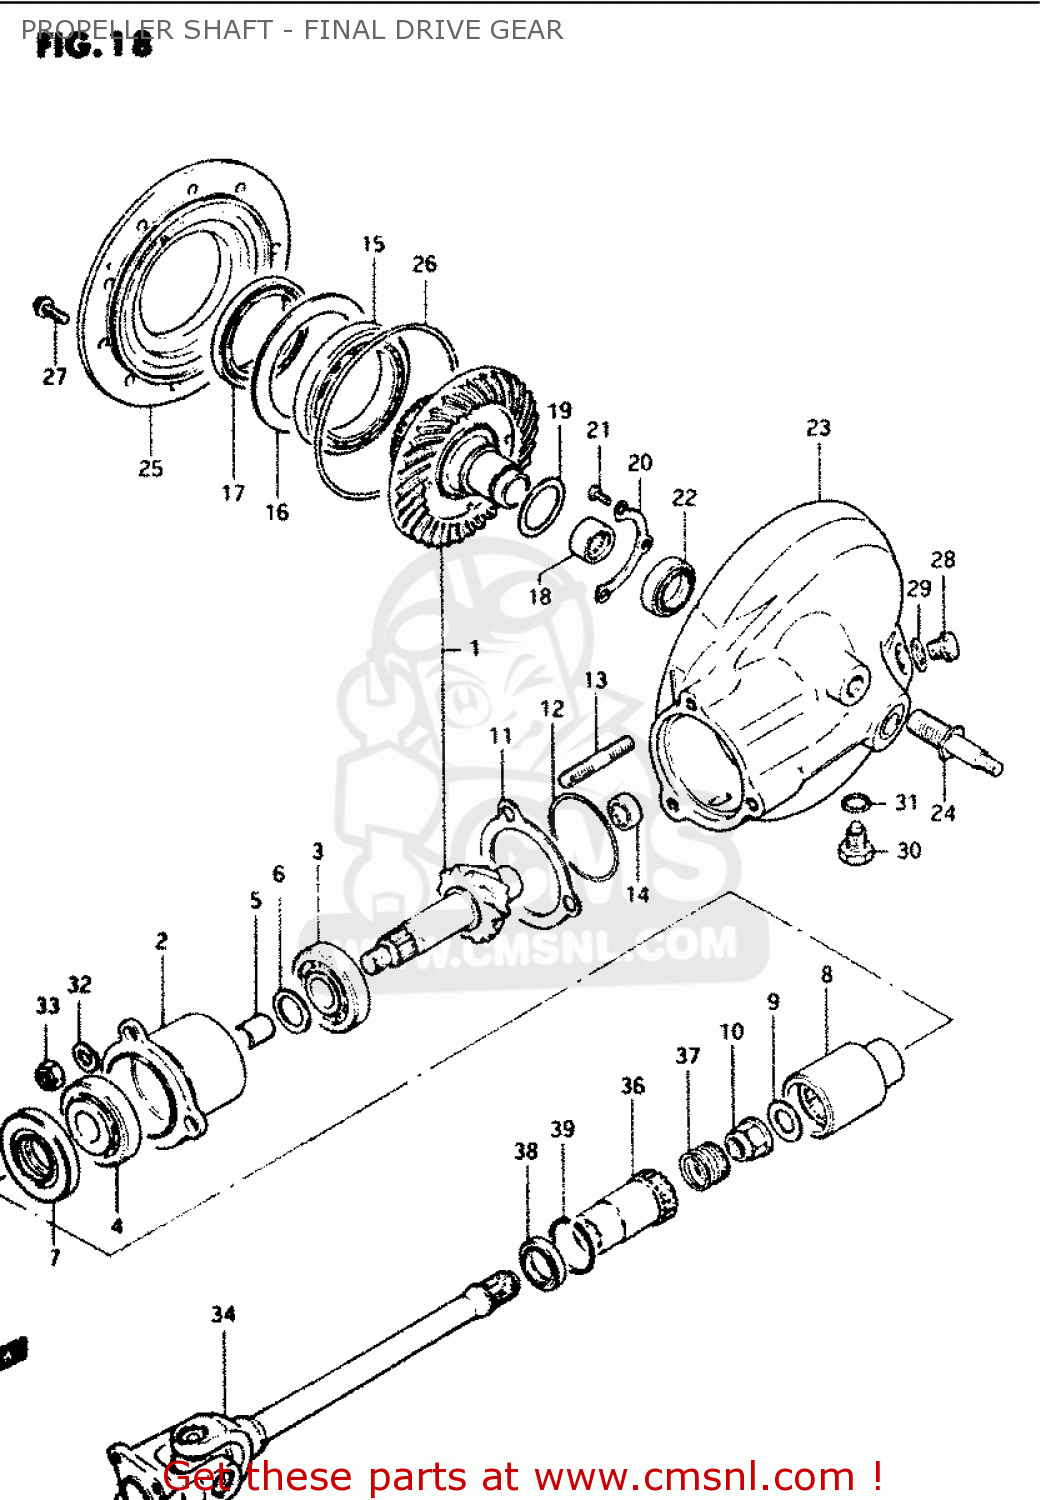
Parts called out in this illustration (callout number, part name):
1	GEAR SET,FINAL BEVEL
2	HOUSING,DRIVE GEAR
3	BEARING(25X52X19.25)
4	BEARING
5	SPACER (25.2X30X3.5)
6	SHIM (25X30X2
7	SEAL,OIL(32X54X7)
8	GEAR,FINAL DRIVE
9	WASHER(14X29X4)
10	NUT
11	SHIM,DRIVE GEAR HOUSING
12	O RING(D:2.4,ID:62.6)
13	STUD 10X30
14	BEARING(24X33X17)
15	BEARING(70X110X13)
16	SHIM,DRIVEN GEAR BEARING
17	SEAL,OIL(70X96X16)
18	BEARING(35X48X23.7)
19	SHIM,FINAL DRIVEN GEAR
20	RETAINER,FINAL DRIVEN GEAR BRG
21	SCREW 6X12
22	SEAL,OIL(30X42X7)
23	CASE ASSEMBLY,FINAL GEAR
24	STUD
25	CASE,FINAL GEAR BEARING
26	O-RING (D:3.1 ID:144.4)
27	BOLT
28	PLUG (14X12)
29	GASKET(14X19.2X2) (NAS)
30	PLUG
31	GASKET(14X19.2X2) (NAS)
32	LOCK WASHER
33	NUT
34	SHAFT ASSEMBLY,PROPELLER
35	BOLT(8X17)
36	COUPLING,PROPELLER SHAFT
37	SPRING
38	SEAL,OIL(30X40.5X5.5)
39	CIRCLIP
